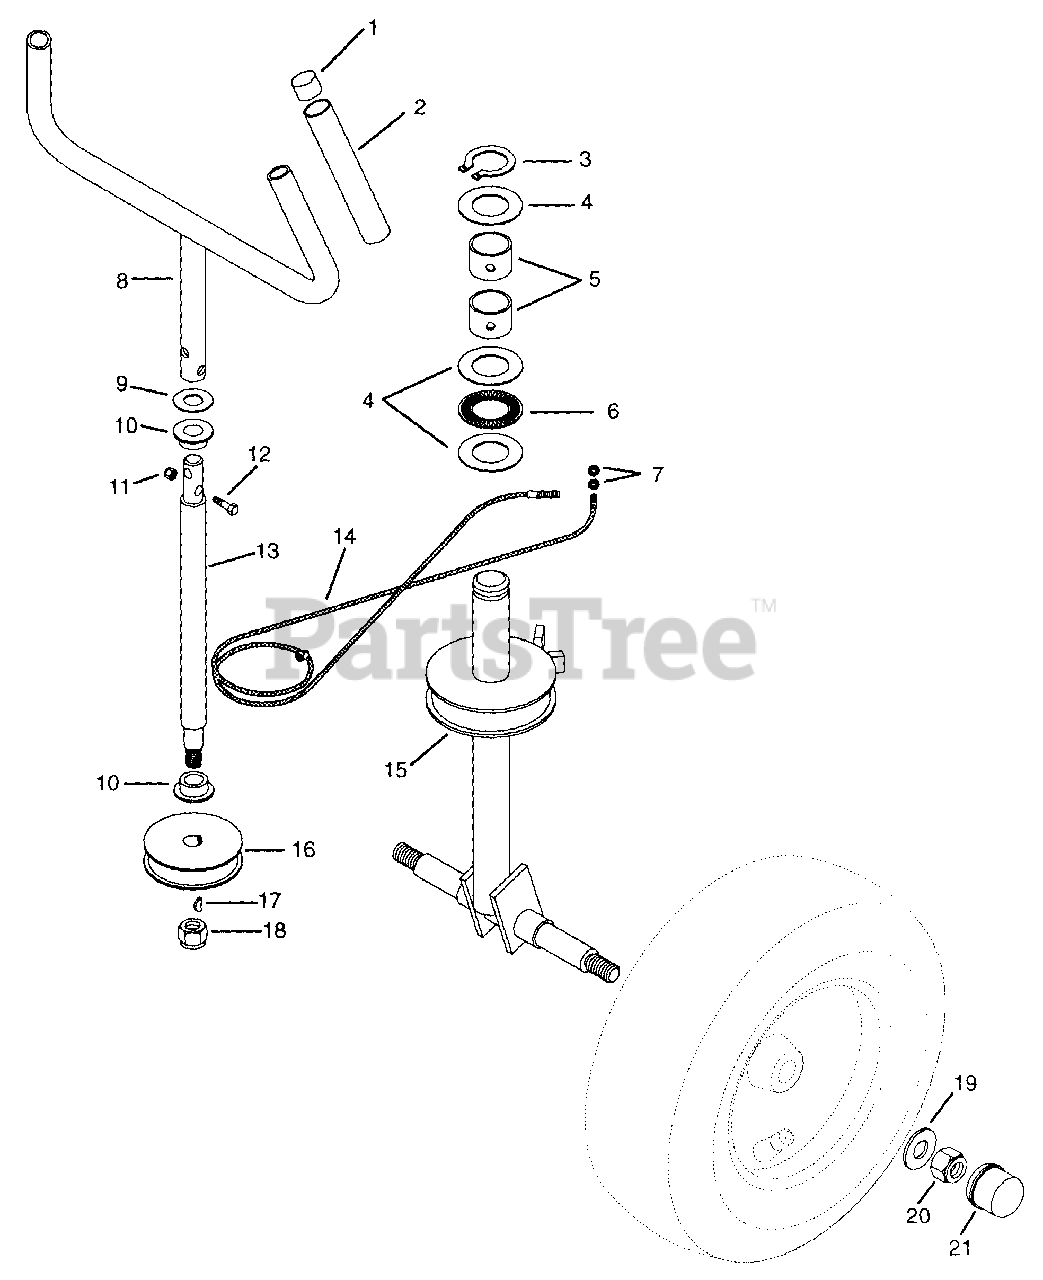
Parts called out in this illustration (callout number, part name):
1	Closure, Vinyl
2	Grip
3	Ring-Retaining-External 1.5 x 1.38
4	Washer-Thrust 1.502 x 2.18 x .063
5	Bearing 1.000 x 1.135 x 1.002
6	Bearing-Needle-Thrust 1.50 x 2.187 x .0781
7	Nut-Jam .312-18
8	Weldment, Handlebar
9	Bearing-Needle-Thrust .752 x 1.24 x .093
10	Bushing-Flange 1.020 x 1.385 x .75 x 1.75
11	Nut-Locking-Nylon .250-20
12	Bolt-Hex .25-20 x 1.38
13	Shaft
14	Cable, Steering
15	Weldment, Caster Wheel
16	Pulley, Cable
17	Key, Woodruff 3/16 x 7/8
18	Nut, Locking 5/8-11
19	Washer-Flat .812 x 1.469 x .134
20	Nut-Locking-Nylon .75-10
21	Cap, Dust
